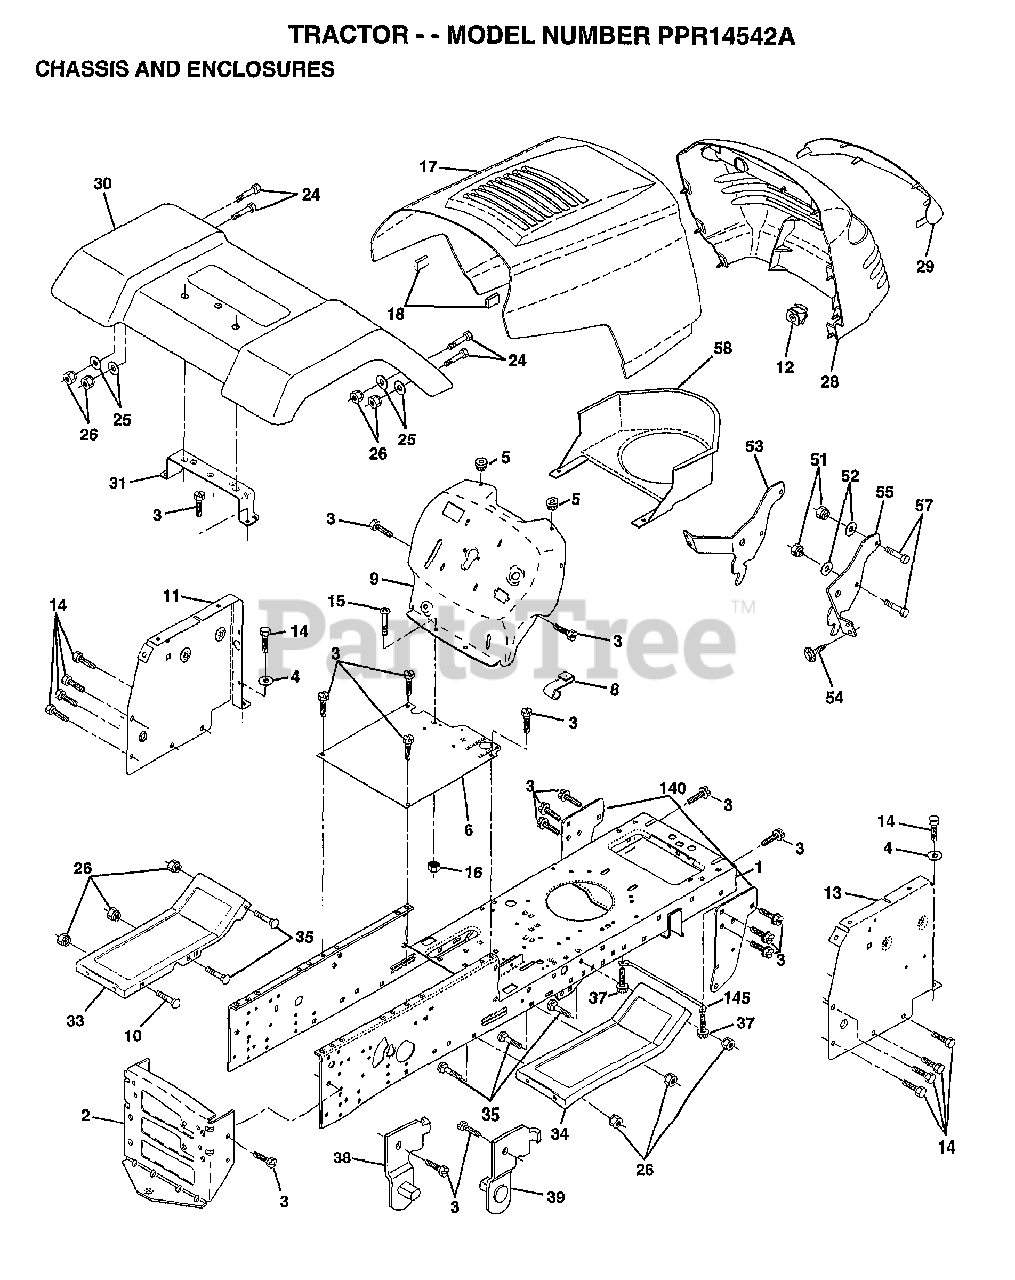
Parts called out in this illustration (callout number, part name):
1	CHASSIS.STAMPING
3	SCREW
4	WASHER
5	BUMPER-HOOD/DASH
6	SADDLE
8	CLIP.RETAINER
9	DASH.SILKSCREEN
11	"PANEL-DASH,LH"
12	CLIP.TINNERMAN
13	PANEL.ASM.SLKSCR.DASH.RH
14	SCREW LT
15	SCREW
17	"HOOD W/TRIM,MS428"
24	BOLT
25	WASHER
26	NUT
28	GRILL
29	GRILLE.LENS
30	FENDER ASM.
31	BRKT FENDER
33	FOOTREST PNT LH
34	FOOTREST.RH.LT/GT
35	BOLT
37	SCREW LT
38	BRACKET ASM LH
39	BRACKET ASM RH
51	NUT
52	WASHER
53	BRACKET.GRILLE.LH
54	SCREW.HEX.WS.HD
55	BRACKET.GRILLE.RH
58	AIR DUCT
140	BRKT SUSPENSION
145	"ROD POVOT,CHASSIS"
